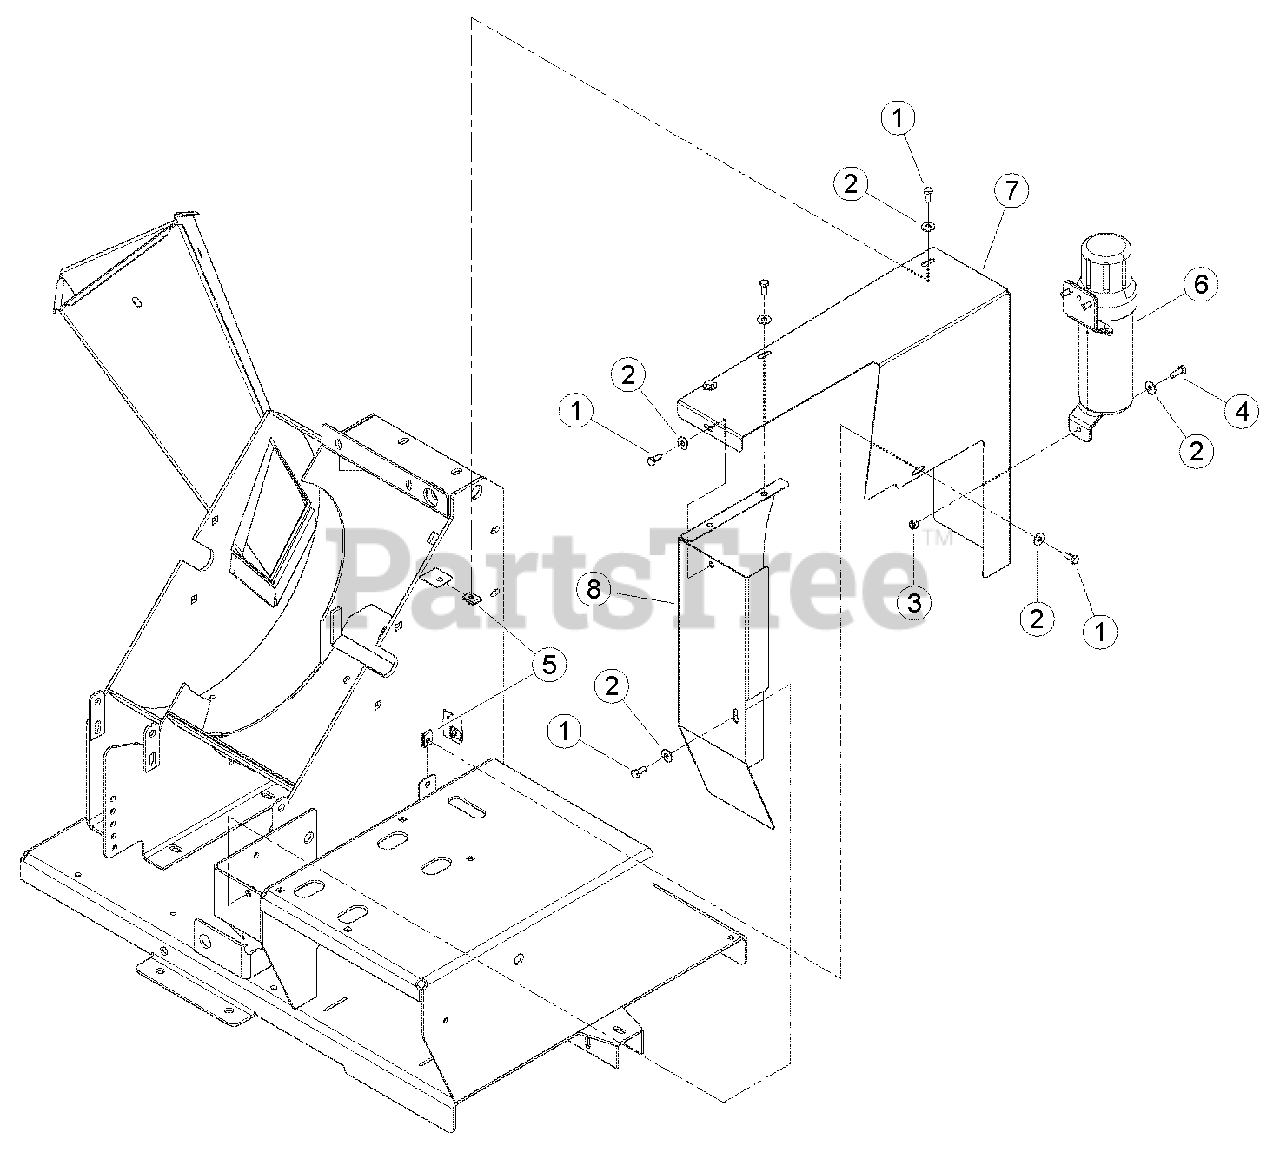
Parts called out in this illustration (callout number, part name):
1	BOLT, 5/16 X 3/4 HEX HD GR5 ZP
2	WASHER, 5/16 FLAT ZP
3	NUT, 5/16 NE NYLOCK ZP
4	BOLT, 5/16 X 7/8 HEX HD NC GR5 ZP
5	NUT, 5/16-18 TINNERMAN U-TYPE
6	CONTAINER, MANUAL
7	SHIELD, BELT
8	WELDMENT, SHIELD
